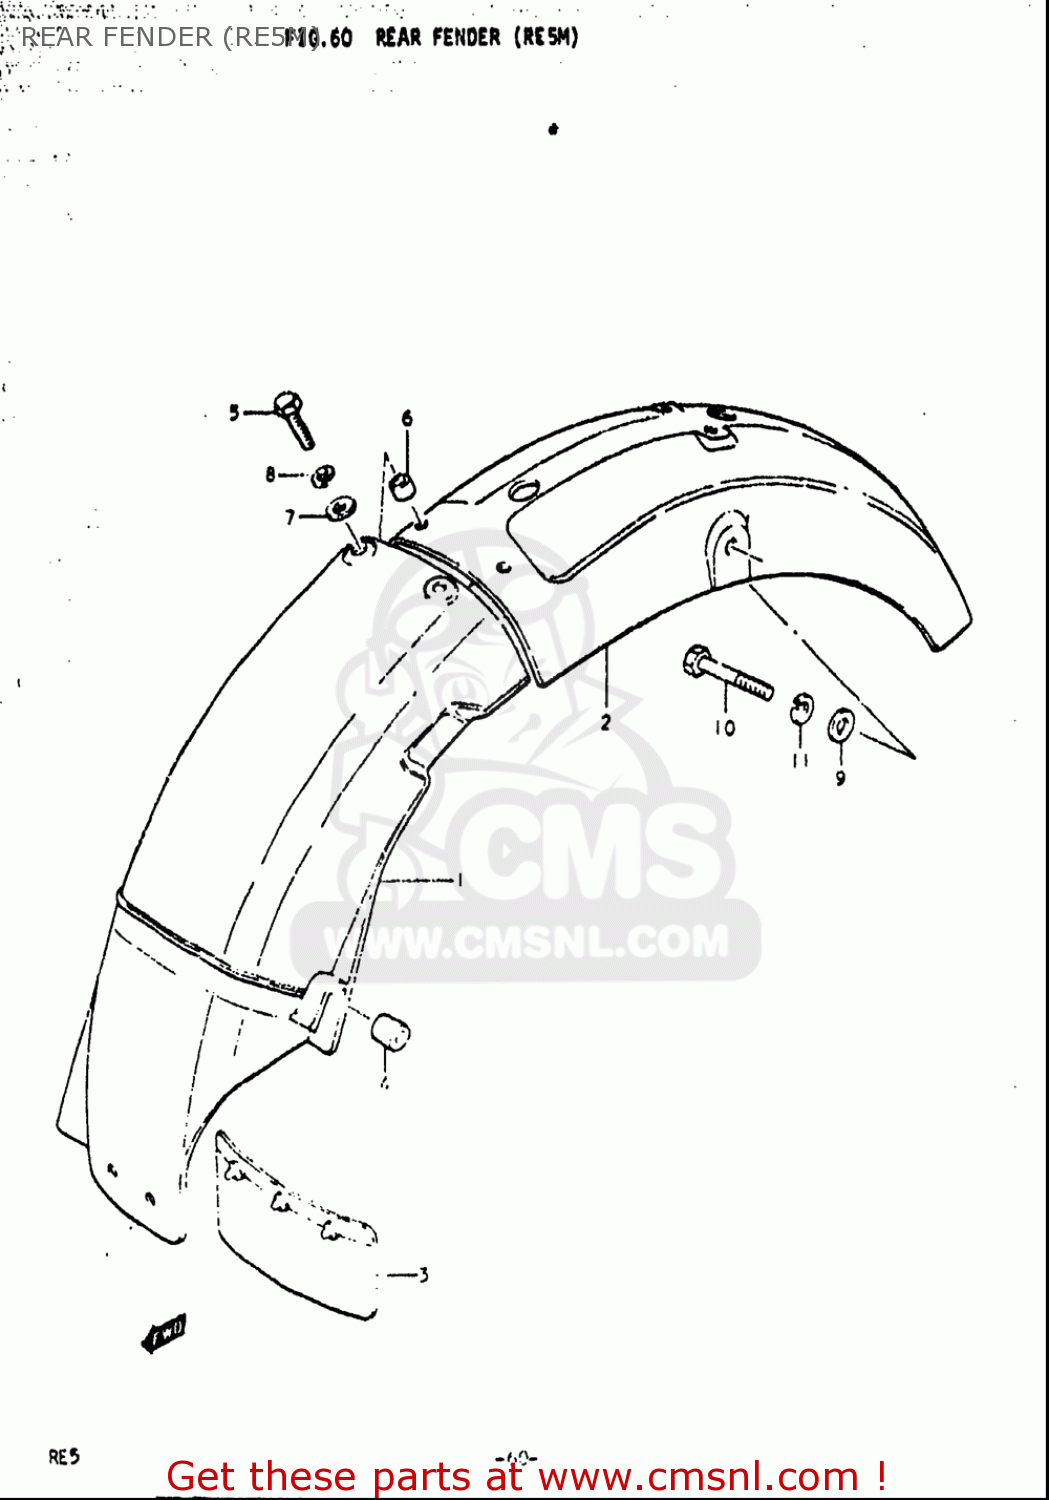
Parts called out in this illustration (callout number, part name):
1	BODY,RR FENDER FR
3	GUIDE,RR FENDER MUD
4	CUSHION
5	BOLT
6	SPACER (6.5X20X5)
7	WASHER
8	WASHER,LOCK
9	WASHER
10	BOLT
11	WASHER,LOCK
